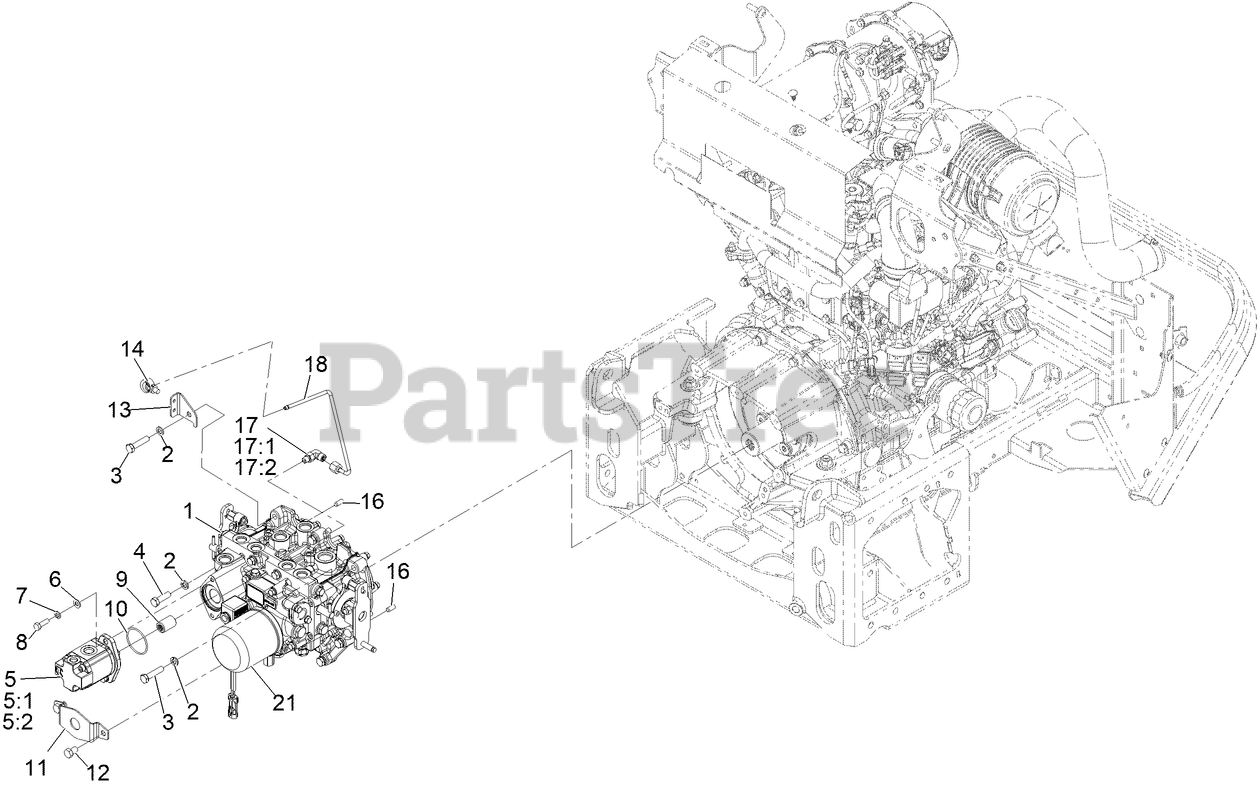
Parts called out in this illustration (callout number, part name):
1	KIT-TRANSMISSION ASM
2	WASHER-LOCK
3	SCREW-HH
4	SCREW-HH
5	HYD GEAR PUMP ASM
5:2	SEAL KIT
6	WASHER-PLAIN
7	WASHER-LOCK
8	SCREW-HH
9	COUPLER-SPLINE
11	SHIELD-SEAL
12	SCREW-HH
13	SUPPORT-TUBE
14	CLIP-TIE
16	PIN-DOWEL
17	FITTING-ELBOW, 90 DEG
17:1	O-RING
17:2	O-RING
18	TUBE ASM
21	FILTER-OIL, HYD
